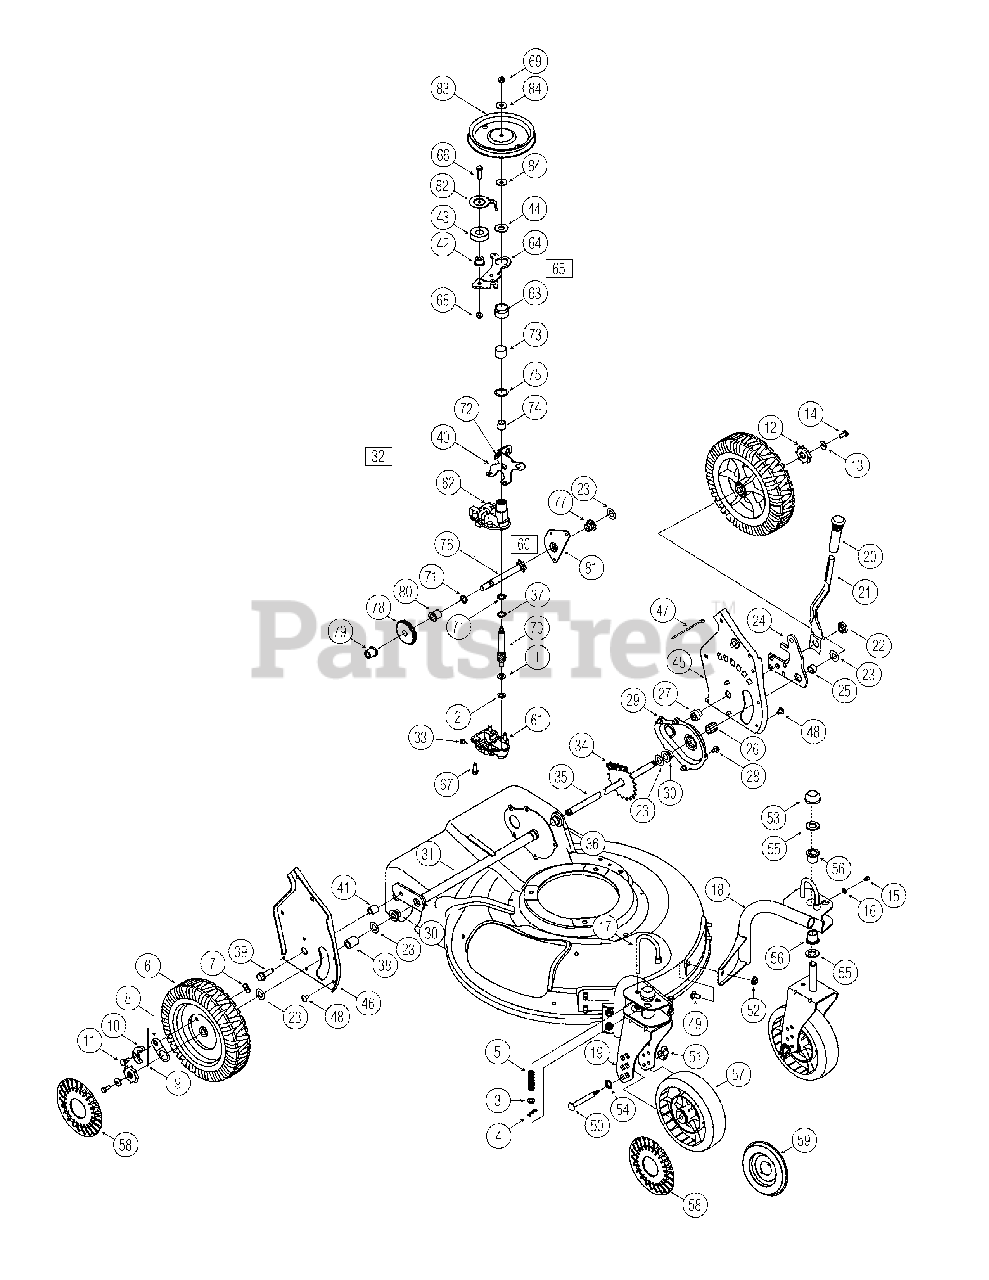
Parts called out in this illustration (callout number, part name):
1	Thrust Washer 3/8 x .70
2	Thrust Washer .388 x .625
3	Flat Washer.330 ID x.630 OD
4	Cotter Pin
5	Compression Spring
6	Wheel 9 x 2
7	Top Lock Tab Weld Nut 1/4-20
8	Ratchet Pawl Plate
9	Plastic Spring Ratchet
10	Pawl RH
10	Pawl LH
11	Shlder Screw.340 ID x.285 OD
12	Wheel Ratchet
13	Bell Washer.265 ID x.75 OD
14	Hex Cap Screw 1/4-20 x .620
15	Grease Fitting
16	Flat Washer.203 ID x.403 OD
17	Wheel Pin Lock
21	Spring Lever
22	Shoulder Nut.825 x .165 Lg.
23	Flat Washer .508 ID x 1.0 OD
24	Pivot Arm Assembly
25	Spacer .510 ID x .70 OD
26	Slv Bearing .504 ID x .830 OD
27	Shlder Spacer, .385ID x .715Lg
28	Tap Screw 1/4-20 x .375
29	Chain Cover Assembly
30	Flge Bearing .506 ID x .590Lg
31	Transmission Axle Assembly
32	Transmission Ass’y Complete
33	Hex Screw 5/16-18
34	Chain
35	Rear Axle Assembly
36	Flge Bearing .506 ID x .715 Lg
37	Flat Washer .885 ID x 1.45 OD
38	Spacer .550 ID x .750 OD
39	Screw 3/8-16 x .25
40	Cable Bracket
41	Spacer .385 ID x .624 OD
42	Flange Spacer
43	Bearing
44	Flat Washer .510 ID x 1.120 OD
48	Screw 1/4-14 x.500
49	Carriage Bolt 5/16-18 x.62
50	Caster Axle
51	Wing Nut
52	Flange Lock Nut 5/16-18
53	Push Cap
54	Wave Washer.531 ID x.781 OD
55	Flat Washer.640 ID x 1.12 OD
56	Flange Bearing
57	Wheel 7 x 2
58	Hubcap - Spoke w/ Hole
59	Hubcap - Radial Spoke
60	Shaft Assembly
61	Lower Housing Assembly
62	Upper Housing Assembly
63	Spacer .915 x 1.125 x .762
64	Idler Bracket
65	Idler Bracket Assembly
66	Hex Cap Screw 1/4-28 x 1.0
67	Hex Screw 1/2-20 x .75
68	Hex Jam Nut 1/4-28
69	Hex Jam Nut 5/16-24
70	Pinion Shaft 10T
71	Oil Seal
72	Extension Spring
73	Bearing Sleeve
74	Bearing
75	Thrst Washer .504 ID x .70 OD
76	Output Shaft 6T
77	Flange Bearing
78	Gear 34T
79	Flange Bearing
80	Flange Bearing
81	Pivot Bracket
82	Belt Keeper
83	Pulley
84	Bell Washer .325 ID x .930 OD+C32
